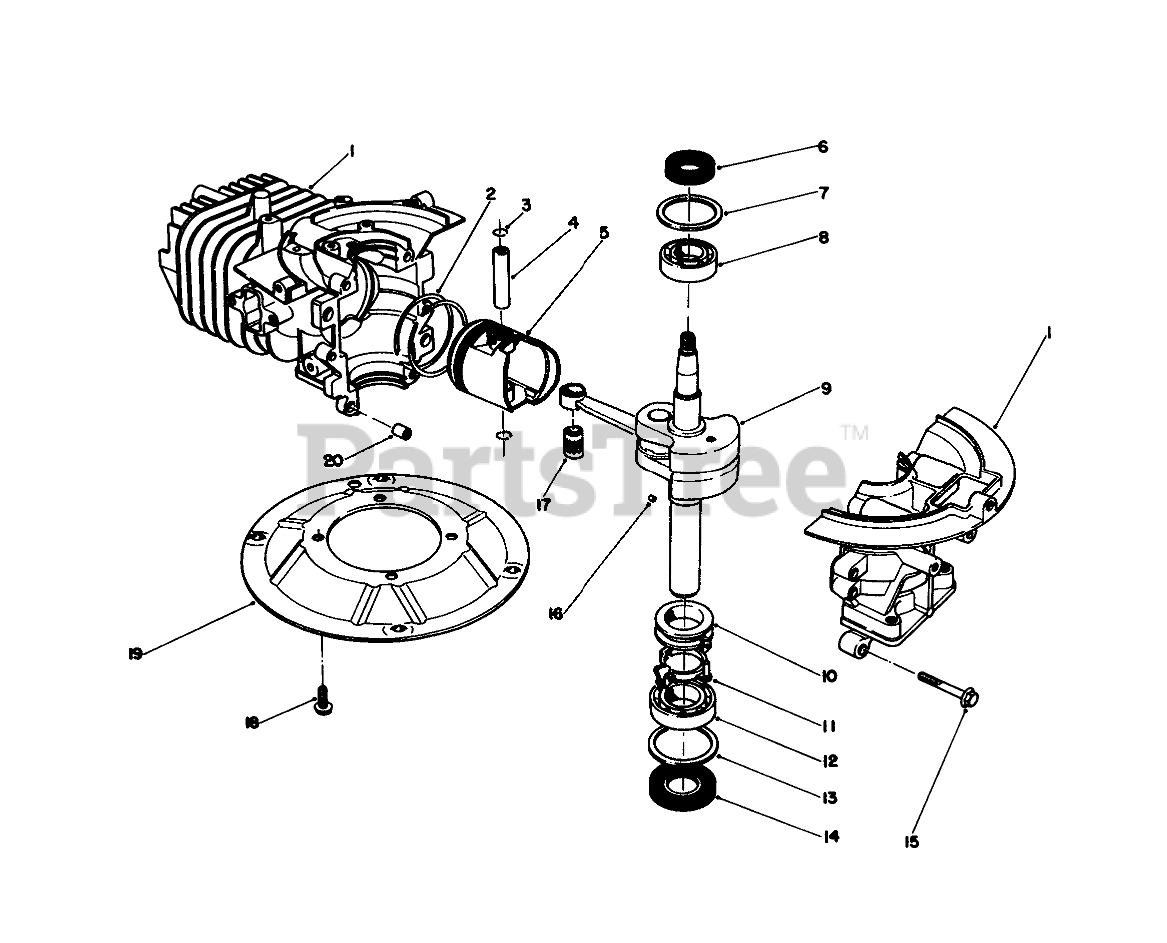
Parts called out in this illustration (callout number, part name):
1	CRANKCASE
2	RING SET
4	PIN-PISTON
5	Piston
6	OIL SEAL
7	WASHER-UPPER
8	BEARING-UPPER
9	Pin-Wrist
10	SPACER
11	BRACKET
12	LOWER BRG
13	WASHER-LOWER
14	SEAL-OIL
17	BEARING
19	PLATE-MOUNTING
